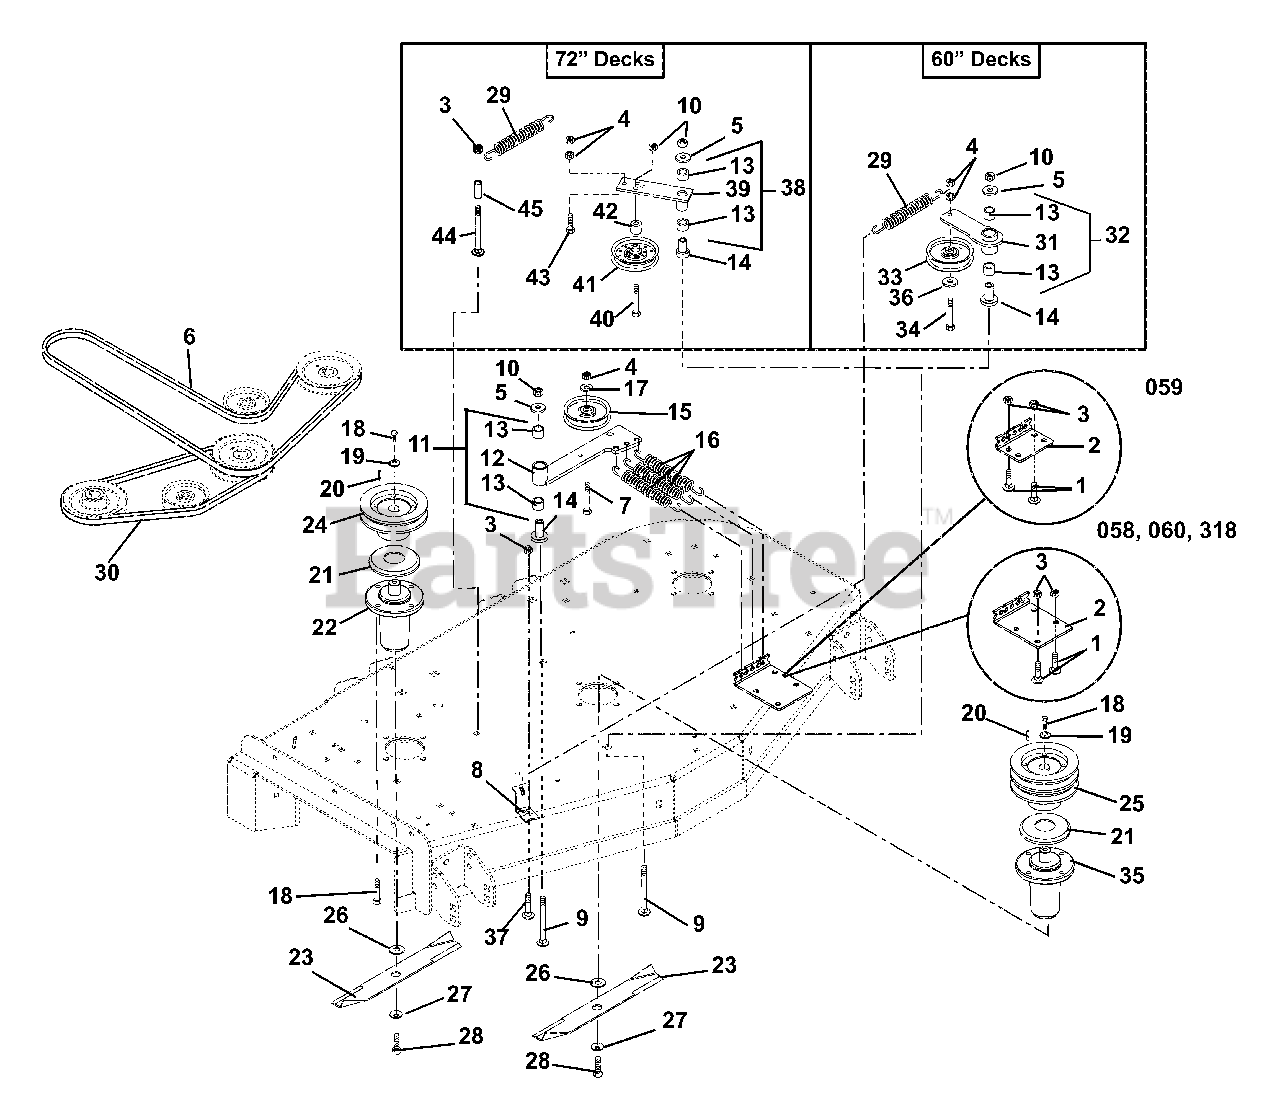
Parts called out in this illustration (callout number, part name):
1	Bolt, Round Head Square Neck .38-16 x .75 Grade 5
2	Bracket, Spring
2	Bracket, Short Spring
3	Nut, Locking Top Flange .38-16
4	Nut, Locking Center .38-16
5	Washer, Flat Steel .531 x 1.25 x .10
6	V-BELT, HB-WRAPPED
6	V-Belt, B-Section 58.25 x .625
7	Bolt-Round Head Square Neck .38-16 x 2.75 Grade 5
8	Anchor, Spring
9	Bolt, Round Head Square Neck .50-13 x 3.50 Grade 5
10	Nut, Locking Top Flange .50-13
11	Assembly-Deck Idler Pivot Arm
12	Weldment, Deck Idler Pivot Arm
13	Bearing, 1.00 x 1.12 x .75
14	Bearing, Pedestal Powdered Metal
15	Idler, Flat 4.00 x .38 (2.32W)
16	Spring, Extension
17	Washer, Flat Steel .375 x 1.125 x .065
18	Bolt, Hex .38-16 x 1.00 Grade 8
19	Washer, Flat Steel .406 x 1.50x .245
20	Key, Square .25 x .25 x 1.00
21	Slinger, Dust
22	Assembly, Maintenance Free Spindle
23	Blade 60" Mower CE
23	Blade, Mower 60" Mulch
23	Blade, Mower-72" (24.50" LG)
23	Blade, Mower
23	Blade, Mower 72" Mulch
24	Weldment, Spindle Sheave 6.00
24	Weldment, Spindle Sheave
25	Sheave, Double (6.25)
25	Sheave, Double (7.25)
26	Washer, Flat .64 x 1.81 x .25
27	Washer, Bellville .63 x 1.625 x .14
28	Bolt, Hex .62-18 x 1.75 Grade 8
29	Spring, Extension
30	V-Belt B-Section 23.94 x .625
30	V-Belt 5L-Section 49.97 x .672
31	Arm, Idler Pivot
32	Asm, Idler Pivot Arm
33	V-Idler, 4.00 x .38
34	Bolt, Hex .38-16 x 2.25 Grade 5
35	Spindle Assembly (Center)
36	Washer, Flat Steel .406 x .812 x .05
37	Bolt, Round Head Square Neck .38-16 x 1.00 Grade 5
38	Assembly, Idler Arm Guard Drive
39	Weldment, Idler Arm Ground Drive
40	Bolt, Hex .38-16 x 6.00 Grade 5
41	Idler, Flat Pulley 6.75 x .51
42	Spacer .513 x .748 x .62
43	Bolt, Hex .38-16 x 1.25 Grade 5
44	Bolt, Round Head Square Neck .38-16 x 2.75 Grade 5
45	Spacer .38 x .625 x 1.50
